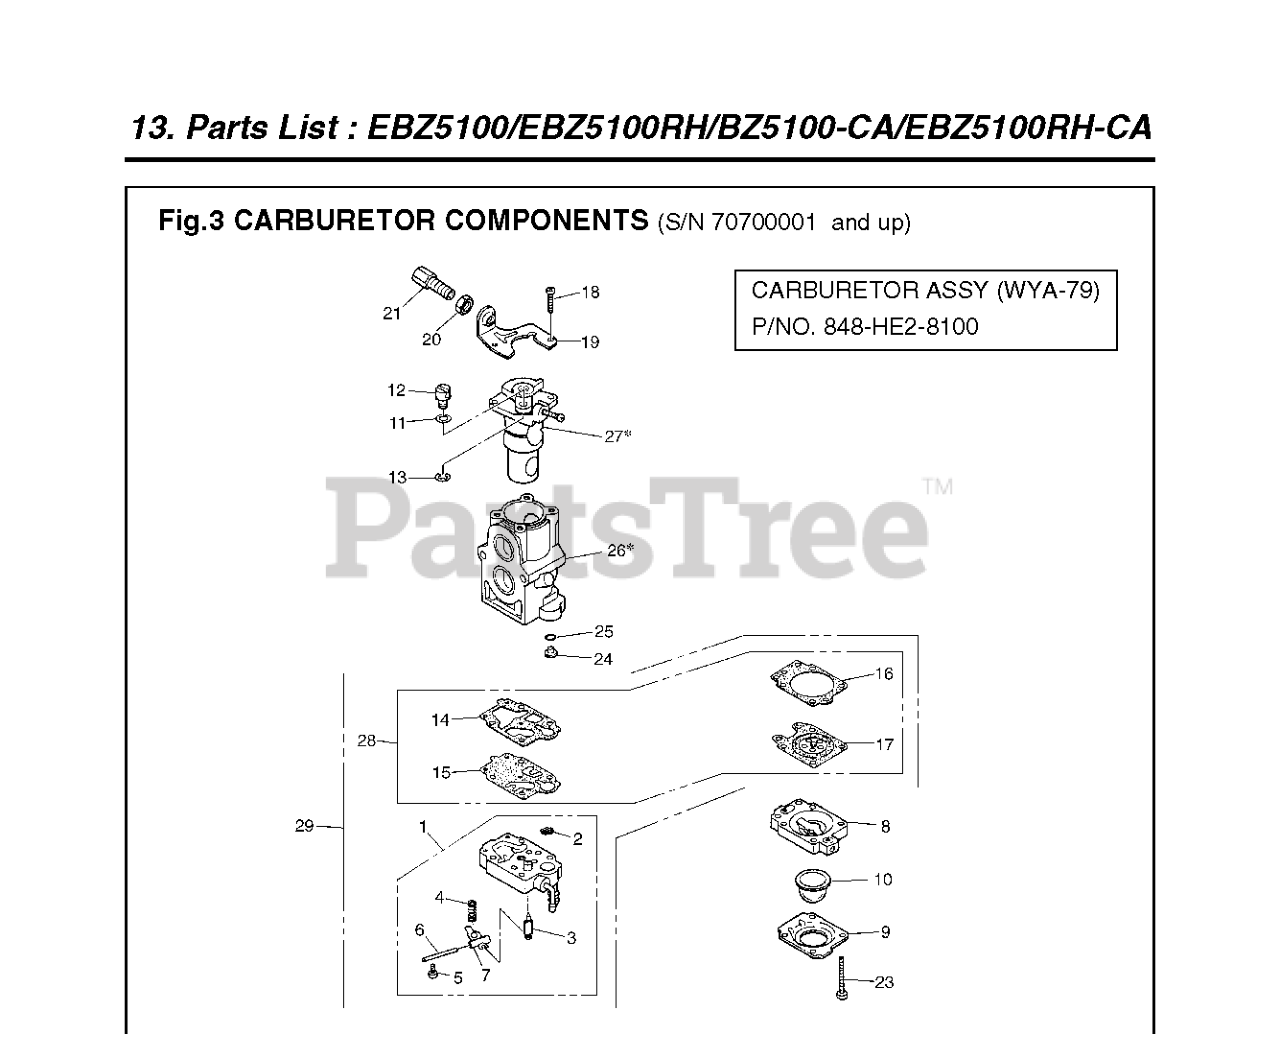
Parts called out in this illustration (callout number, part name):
1	BODY-A-PUMP
9	1OVER
11	WASHER
12	SWIVEL
13	RING
15	DIAPHRAGM
17	DIAPHRAGM
18	SCREW
19	BRACKET
20	NUT
21	ADJUSTER
24	JET (RPLS T104881250)
26	CARBURETOR***
27	CARBURETOR***
28	GASKET KIT
29	REBUILD KIT
